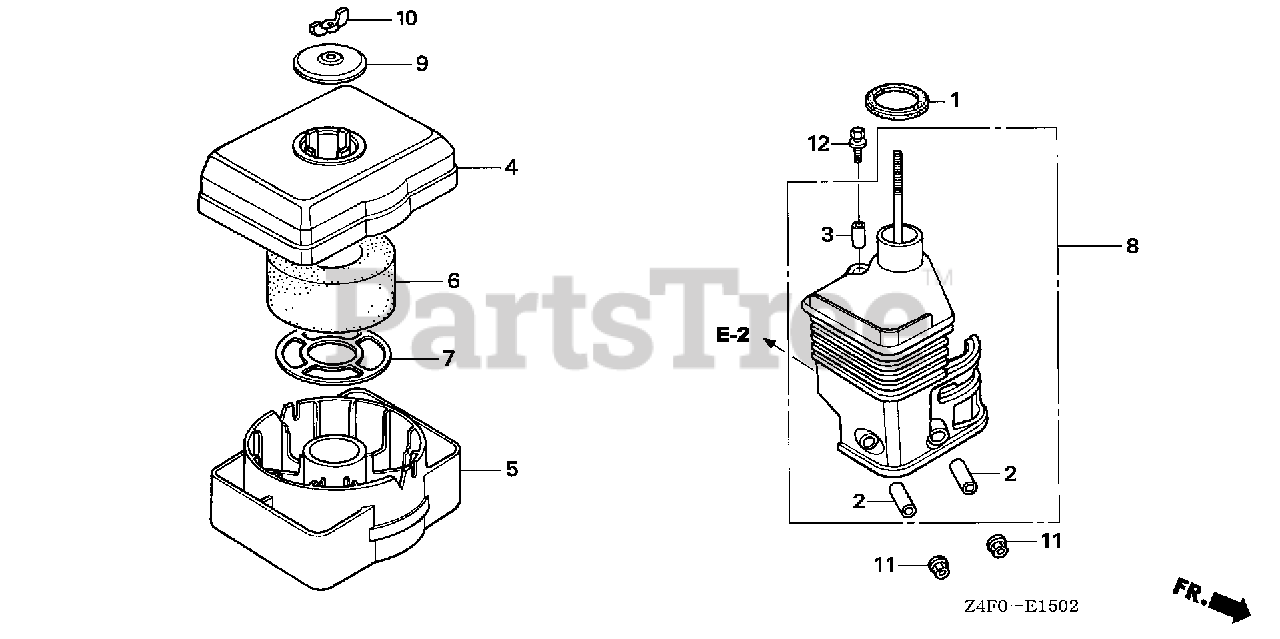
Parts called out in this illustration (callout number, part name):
1	GASKET, ELBOW
2	COLLAR, AIR CLEANER
3	COLLAR B, AIR CLEANER
4	BODY, CLEANER (OIL BATH)
5	PAN, CLEANER OIL (OIL BATH)
6	ELEMENT, AIR CLEANER (OIL BATH)
7	GRID, AIR CLEANER
8	ELBOW, AIR CLEANER
9	CAP, CLEANER
10	NUT, TOOL BOX SETTING
11	NUT, FLANGE (6MM)
12	BOLT, FLANGE (6X20)
